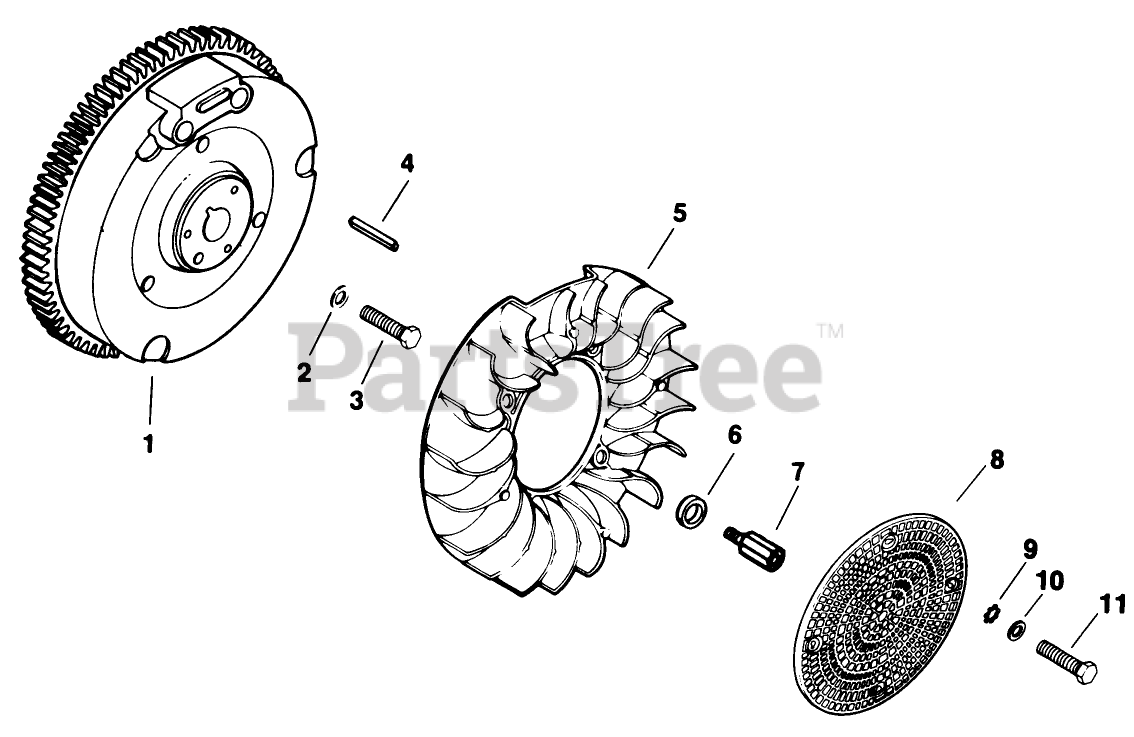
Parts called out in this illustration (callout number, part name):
1	Flywheel
2	Washer-Flat
3	Screw-H.C.
4	Key
8	Screen-Grass
9	Washer-Lock
10	Washer
11	Screw-T.H.
